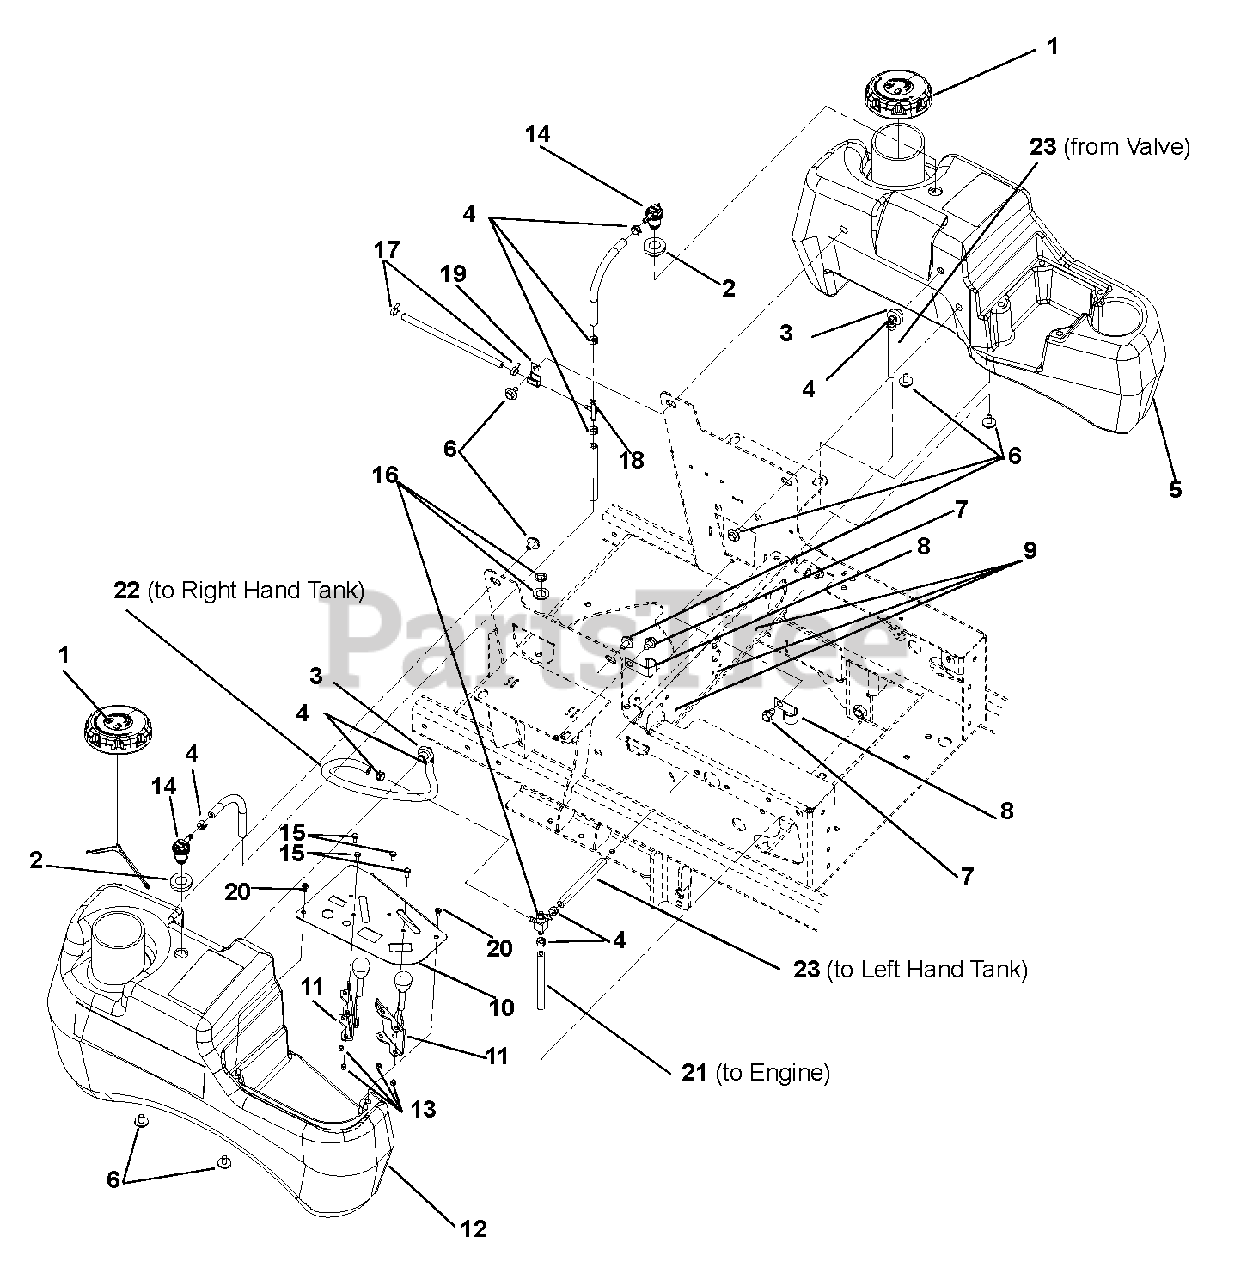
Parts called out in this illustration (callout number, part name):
1	Cap, Fuel Vent-in Autolock
2	Grommet, Remote Vent Nitrile
3	Assembly, Medium Tank Fuel Pick-up
4	Clamp, Fuel Line
5	Tank, Left Hand Medium Gravely Fuel
6	Bolt, SEMS .31-18 x .62
7	Screw, Tapping Hex Washer Head Thread Rolling .38-16 x .50
9	Cable Tie
10	PT100 Control Panel, Black
11	Cable, PT100 Throttle Control
12	Tank, RH Medium Gravely Fuel
13	Nut, Locking, Nylon 10-24 w/Insert
14	Valve, Combination
15	Screw, Machine Hex Washer Head 10-24 x .50
16	Valve, Fuel
17	Clamp, Hose, Spring .188
18	Tee, 1/4HS Run x 3/16HS Branch
20	Screw, Machine HWH Stainless 10-24 x .38
21	Hose, .25 Low-Perm Bulk Gas
22	Hose, .25 Low-Perm Bulk Gas
23	Hose, .25 Low-Perm Bulk Gas
